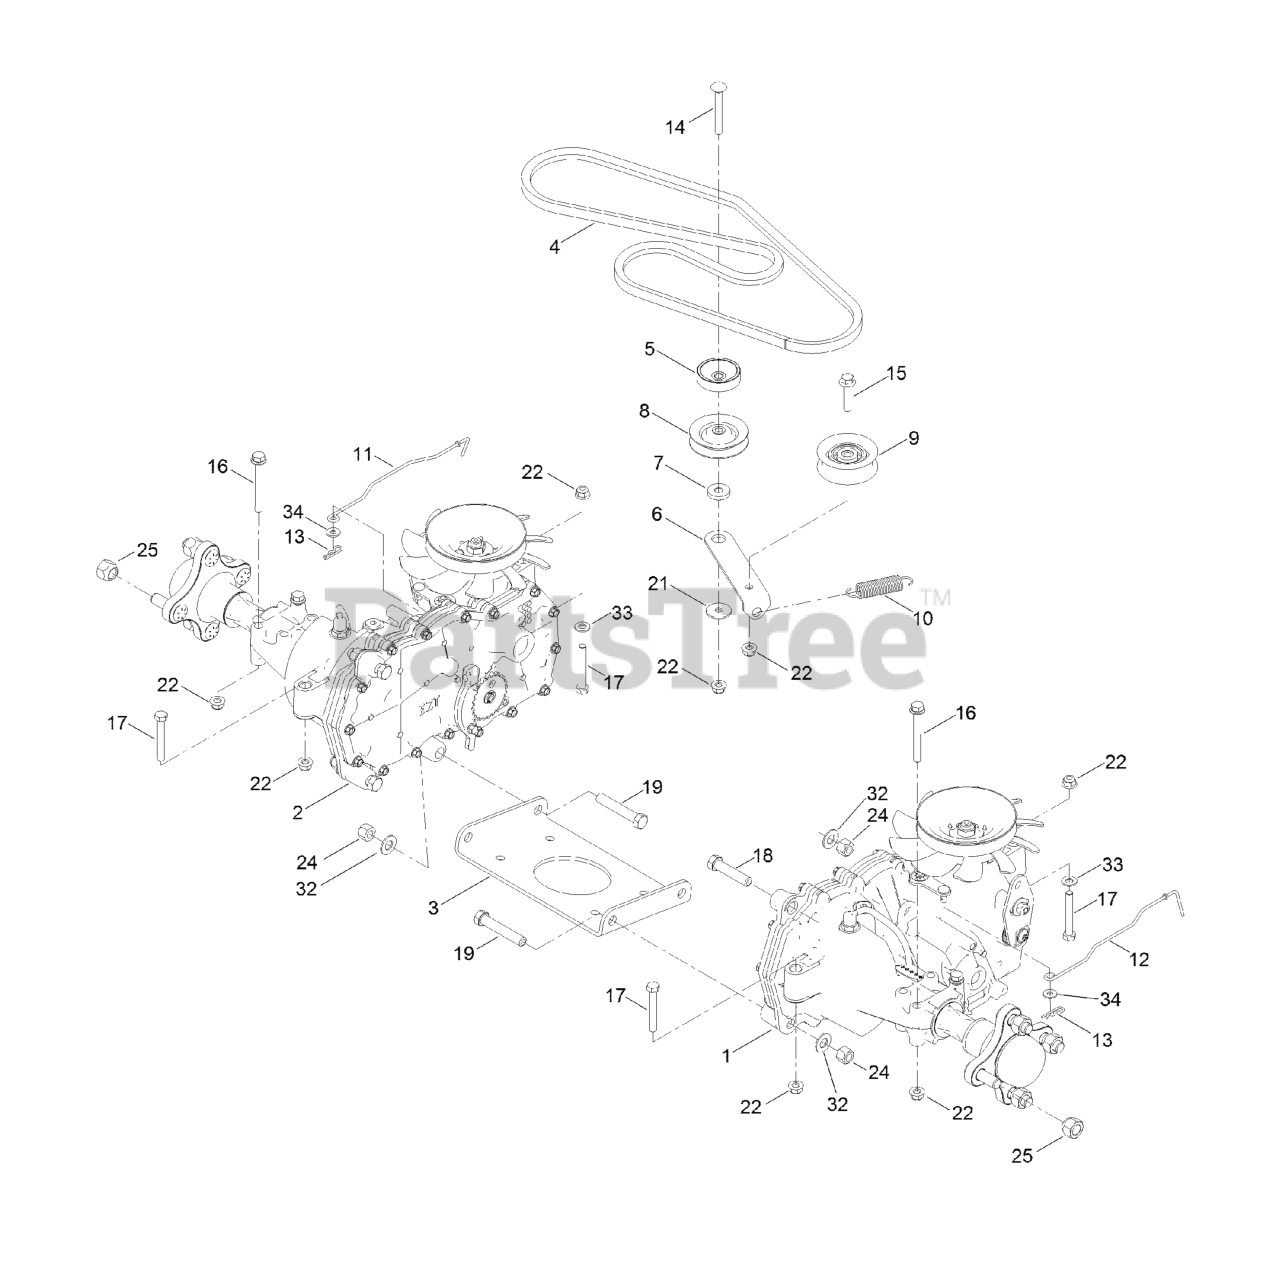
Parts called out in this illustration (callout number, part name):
1	LH HYDRO TRANSAXLE ASM
2	RH HYDRO TRANSAXLE ASM
3	CROSSPLATE-HYDRO
6	Arm-Idler
7	SPACER-ARM, IDLER
9	Pulley-Idler, Flat
10	Spring-Return, Pedal
11	Rod- Bypass,RH
12	Rod- Bypass,LH
14	SCREW-CARR
15	SCREW-HHF
16	SCREW-HHF
17	SCREW-HH
18	SCREW-HH
19	SCREW-HH
21	WASHER-PIVOT
22	NUT-HF, NI
24	NUT-LOCK, NI
25	NUT-LUG
32	WASHER-FLAT
33	WASHER-PLAIN
